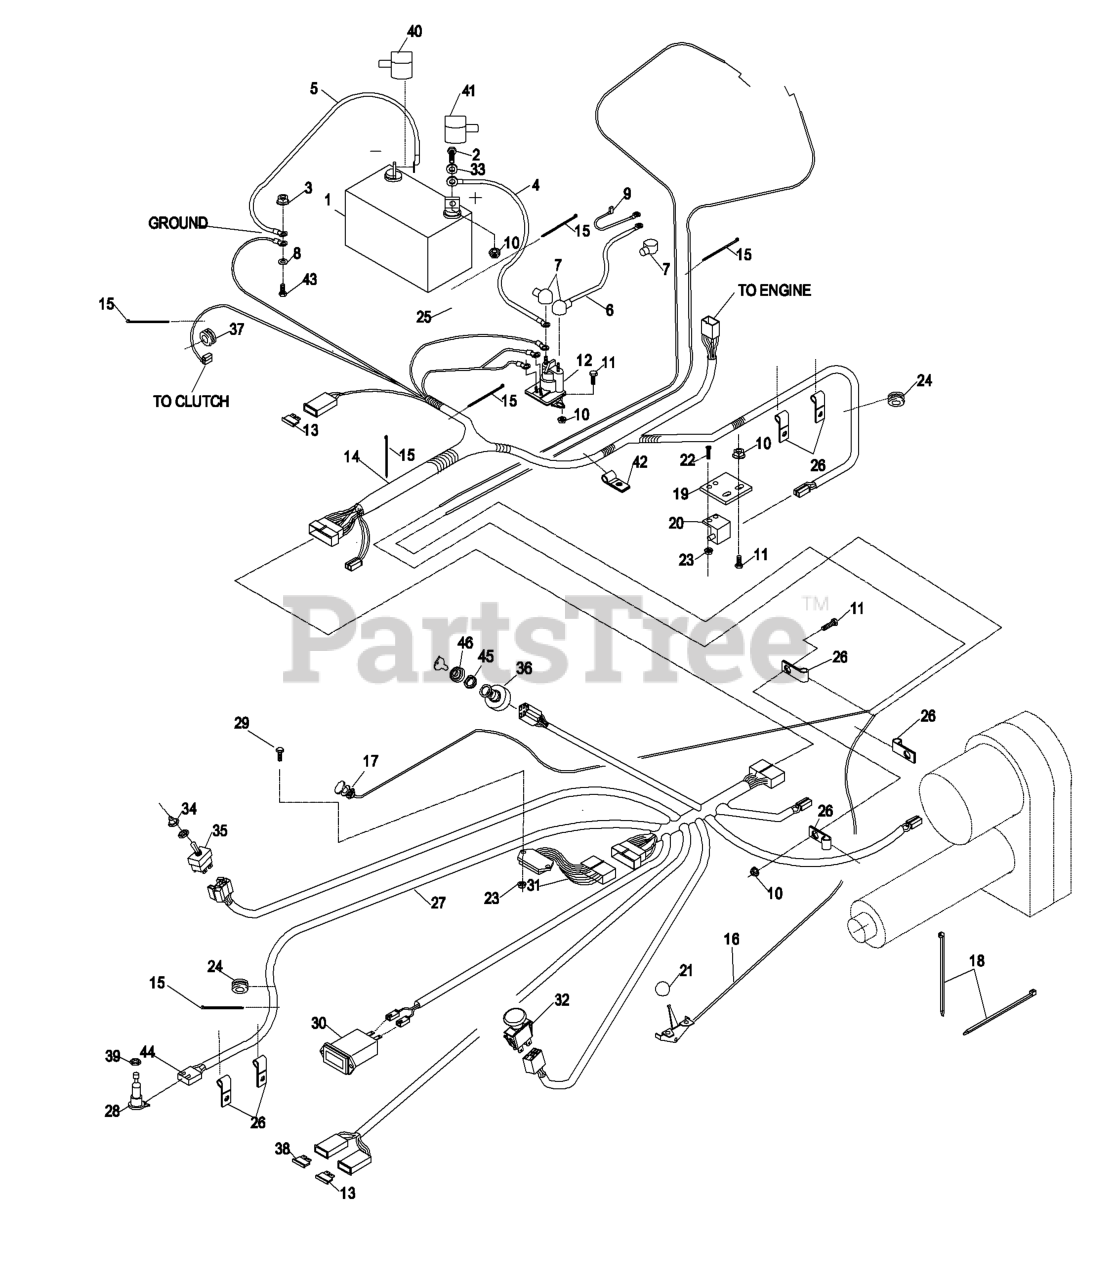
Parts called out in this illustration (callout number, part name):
2	SCREW-HH
5	WIRE-GROUND
6	WIRE,BATTERY POSITIVE
7	INSULATOR-SOLENOID
8	WASHER-SPRING
11	SCREW-HH
13	FUSE-BLADE TYPE, 20 AMP
15	TIE-CABLE
16	THROTTLE CABLE ASM
17	CONTROL-CHOKE
18	TIE-PLASTIC
19	BRACKET,SAFETY SWITCH
20	SWITCH-OPEN, NORMALLY
21	KNOB-BALL
22	10-24 X 5/8 FLT HD MS
23	NUT-LOCK, NI
24	GROMMET
26	CLIP-LOOM
27	HARNESS,CONSOLE WIRING
28	SWITCH,PUSH BUTTON
30	METER-HOUR
31	MODULE,OPC
33	WASHER-FLAT
34	BOOT-SWITCH, TOGGLE
35	SWITCH-TOGGLE, DPDT
36	SWITCH,IGNITION
37	GROMMET
38	FUSE-BLADE TYPE, 30 AMP
41	INSULATOR, BATTERY -
42	CLIP-LOOM
43	SCREW-HH
44	CONNECTOR,PACKARD 2 WAY
45	NUT-SWITCH, IGNITION
46	SEAL-SWITCH, IGNITION
